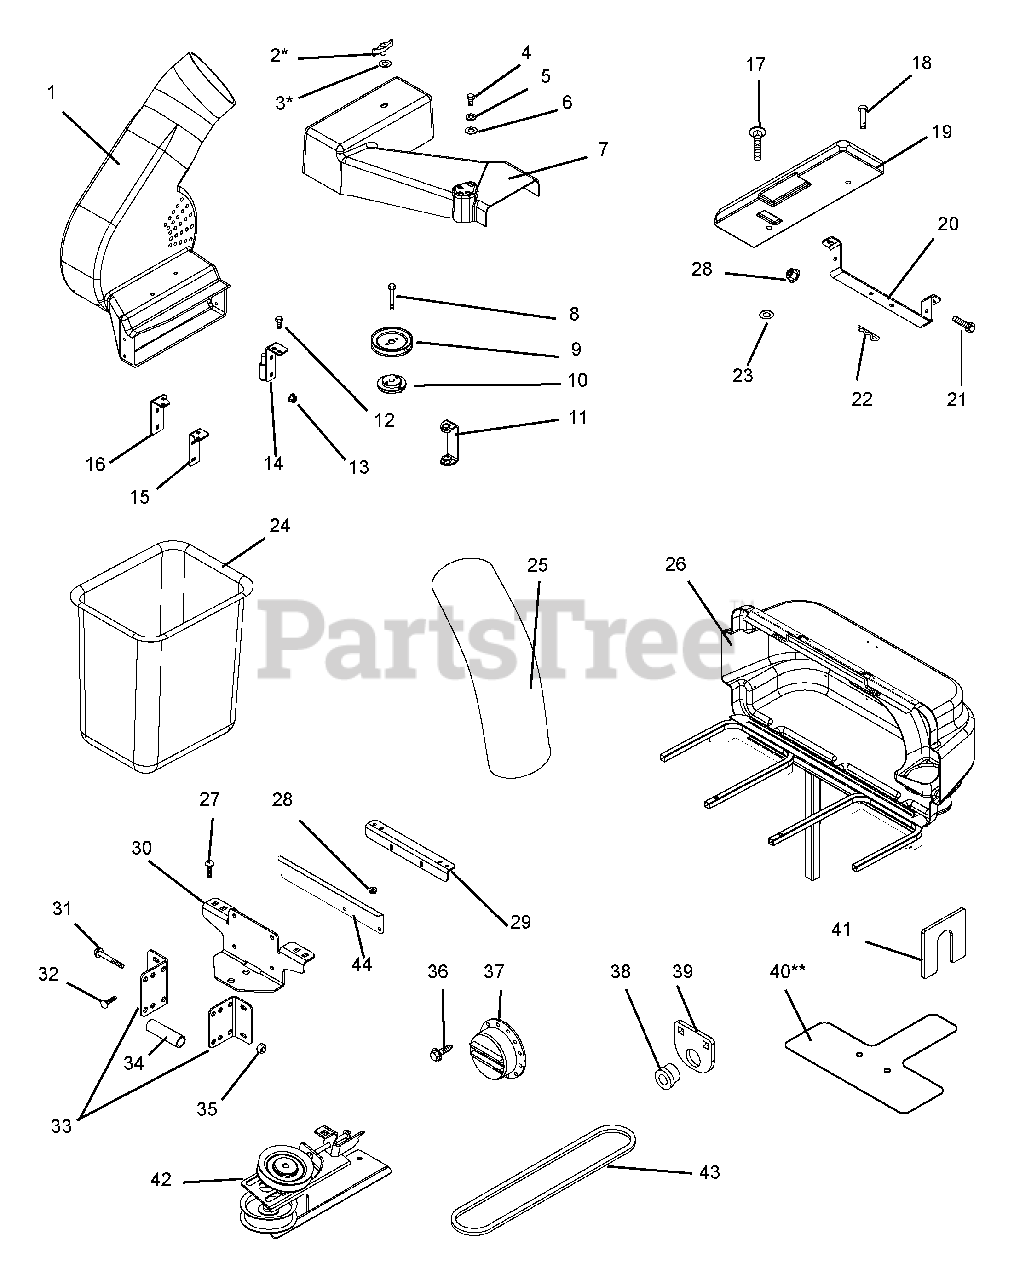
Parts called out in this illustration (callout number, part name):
1	Blower Assembly
2	Wing Knob
3	3/8" x 1-1/2" Washer
4	3/8" x 3/4' Hex Bolt
5	3/8" Lock Washer
6	7/16" x 1" Flat Washer
7	Belt Cover
8	3/8" x 1-3/4" Hex Bolt
9	3-Inch Sheave
9	4-Inch Sheave
10	Sheave Adapter
11	Cover Spacer
12	1/4" x 3/4" Hex Bolt
13	1/4" Top Lock Flange Nut
14	Rear Mount Weldment Bracket
15	Front Bracket
16	Front Mount Weldment Bracket
17	3/8" x 1" Round Head Square Neck Bolt
18	Clevis Pin
19	Counterweight
20	Counterweight Bracket
21	3/8" x 1" Hex Bolt
22	Hair Pin
23	1/2" x 1-5/8" Flat Washer
24	Grass Bagger Basket
25	Hose
26	Cover Assembly
27	3/8" x 2-1/2" Round Head Square Bolt
28	3/8" Top Lock Flange Nut
29	Angle Bracket
30	Trailer Hitch
31	1/2" x 3" Hex Bolt
32	3/8" x 1-1/4" Round Head Square Neck Bolt
33	Bagger Mount Bracket
34	Pivot Spacer
35	1/2" Top Lock Flange Nut
36	Self-Tapping Screw
37	Exhaust Deflector
38	Flange Bushing
39	Rear Pivot Bracket
40	Finger Guard
41	Lift Plate
42	Idler Assembly
43	40- and 44-Inch V-Belt
43	48- and 52-Inch V-Belt
44	Exhaust Deflector
